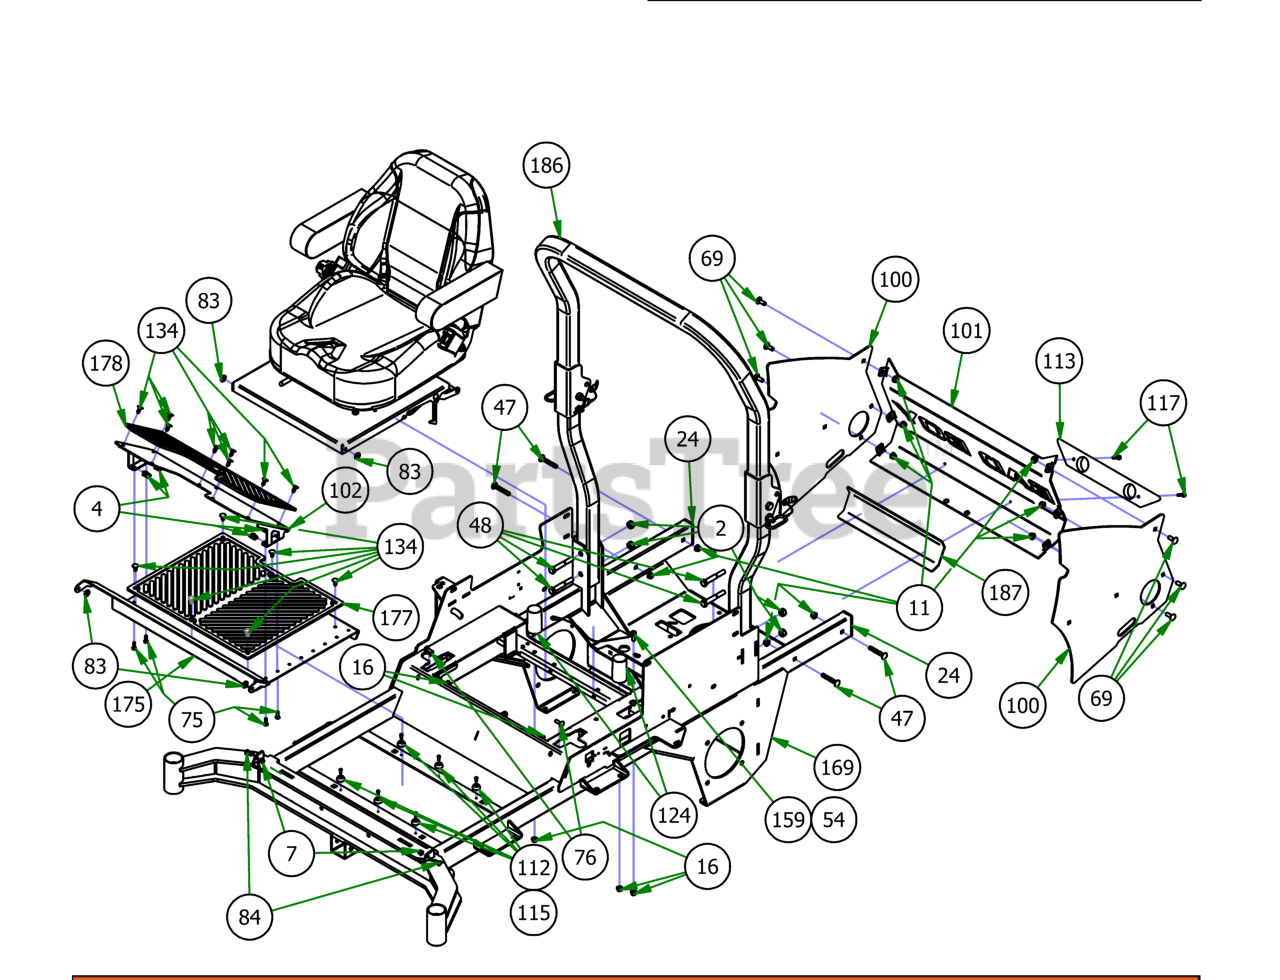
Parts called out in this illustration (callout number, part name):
2	1/2" Center Lock Nut
4	1/4-20 Cage Nut
7	1/4-20 Nylon Insert flange Nut
11	3/8" Nylock Flange Nut
16	5/16" Nylon Flange Nut
19	5/16" Flange Nut
21	5/16-18 Nylock Jam Nut 1/2 Nut
24	1 1/2 x 3 Frame Plug
44	M6-1.0 X 16MM Hex Bolt
47	3/8" x 2 1/2" Carriage Bolt
48	1/2-13 X 3.25 Hex Bolt - Grade 5
54	5/16" x 1" Bolt
65	5/16" x 1 1/4" Carriage Bolt
69	3/8" x 1" Carriage Bolt
75	1/4" x 3/4" Hex Bolt
76	5/16" x 1" Carriage Bolt
83	.360 ID Plastic Washer
84	1/4" x 3/4" Carriage Bolt
99	2019 Outlaw Seat Plate
100	2019 Rebel Rear Cover Side Plate
101	2019 Vertical Rear Cover Tailgate Plate
102	2019 Outlaw Adjustable Foot Plate
109	Seat Latch Rod Assembly
112	Button Bumper
113	2017 XP Bumper
115	#10 x 1/2" Self Tapping Screw
117	1/4 x 1 Hex Head Tek screw
124	2019 Bad Boy X Cylindrical Seat Mount
128	Brake Spring
134	Ratchet Fastener
159	Seat Cable
160	2019 Outlaw EPA Cannister Assembly
169	2019 Rebel Frame - Powdercoated
170	2021 Rebel Seat w/ Seatbelt
171	2019 Renegade Seat
175	2019 Outlaw Floorboard
177	OUTLAW2019_FLOORMAT
178	FLOORMAT_OUTLAW_2019
186	2019 2X2 Folding ROPS
187	Heat Shield (Fiberglass Adhesive)
